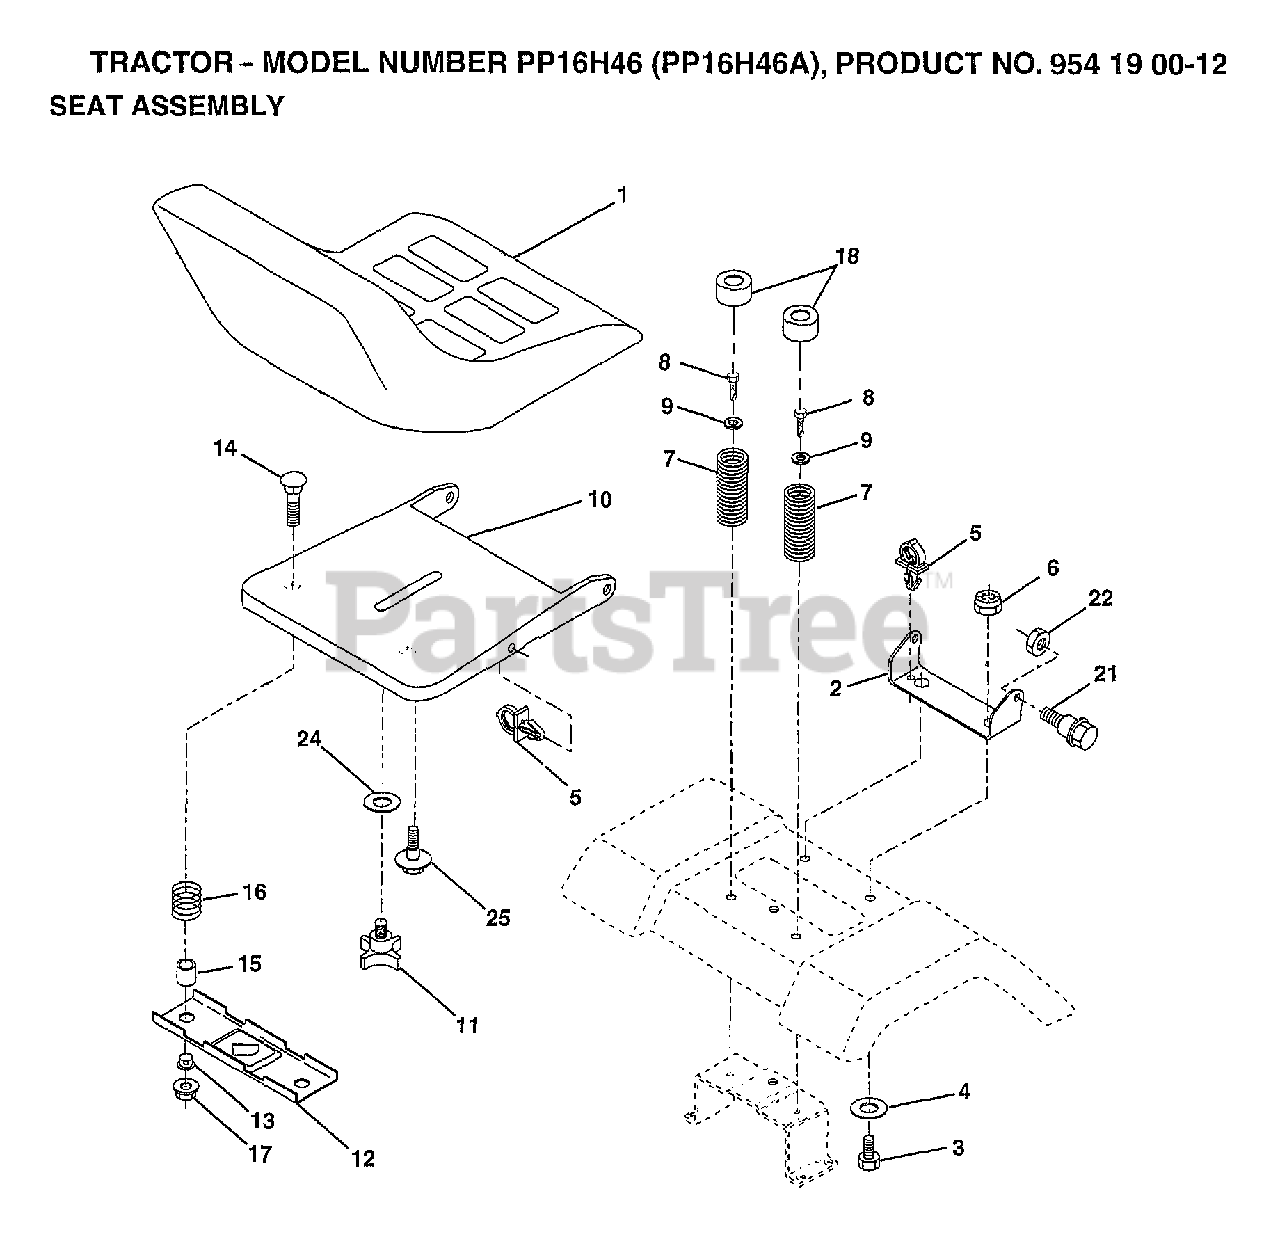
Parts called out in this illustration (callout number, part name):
1	SEAT.2500/1516.BK
2	BRACKET PVT SEAT
3	BOLT
4	WASHER PM
5	CLIP.PUSH-IN.HING
6	NUT
7	SPRING, COMPRESSION, SEAT
8	SCREW GTV
9	WASHER
10	PAN-SEAT
11	"KNOB 1/2"" YT"
12	BRKT SWITCH
13	BUSHING
15	SPACER SPLIT
16	SPRING COMPRESSED
18	CAP SPRING
21	"BOLT,SHOULDER"
22	NUT
24	WASHER
25	"BOLT,SHOULDER"
